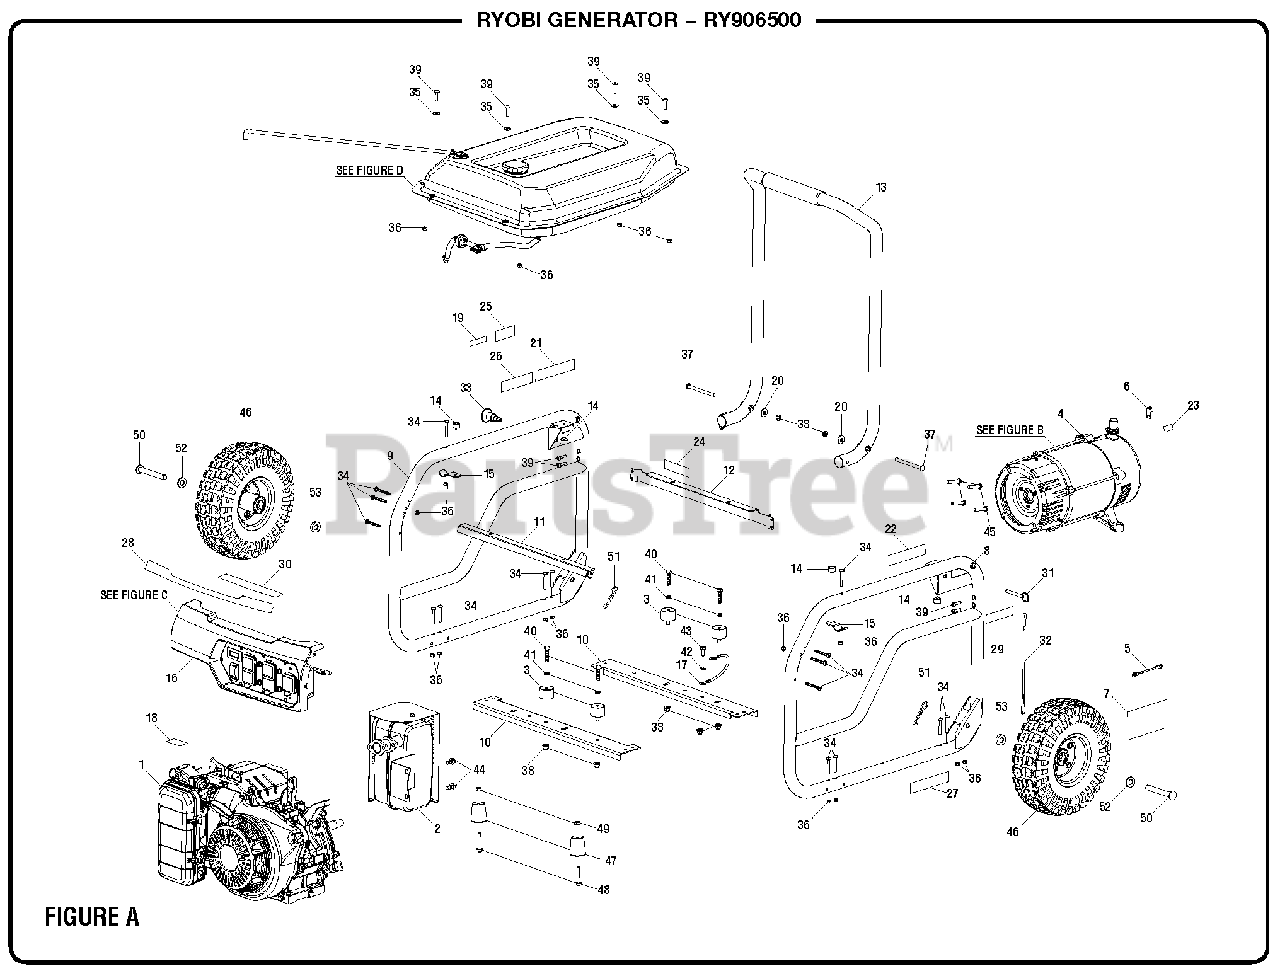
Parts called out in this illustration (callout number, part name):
1	Engine (Honda)
2	Muffler Assembly
4	Generator Head Assembly (See Figure B)
5	Bonding Wire
6	Ground Lug
7	Rubber Sheet
8	Frame Assembly (Right)
9	Frame Assembly (Left)
10	Cross Bar
11	Fuel Tank Support (Front)
12	Fuel Tank Support (Rear)
13	Handle Assembly
14	Handle Bumper
15	Handle Rest Tab
16	Control Panel Assembly (See Figure C)
17	Ground Wire Assembly
18	Choke Label
19	Inquiries Label
21	Fire Distance Label
22	Fire Danger Label
23	Ground Label
24	Ground Warning Label
25	Pull Pin Release Label
26	Hot Surface Label
27	Lubricant Label
28	Performance Label
29	Lock Pin Label
30	Quick Start Label
31	Release Pin
33	Handle Lock Assembly
34	Bolt (M6 x 50 mm, Torx Pan Hd. T30)
35	Washer (M6)
36	Lock Nut (M6)
37	Bolt (M8 x 98 mm, Flat Hd.)
38	Lock Nut (M8)
39	Bolt (M6 x 25 mm, Torx Pan Hd.)
40	Bolt (M8 x 35 mm, Hex Hd.)
41	Washer (M8)
42	Star Washer (M8)
43	Bolt (M8 x 15 mm, Hex Hd.)
44	Bolt (5/16-24 x 0.6 in.)
45	Bolt (3/8-16 x 1 in.)
48	Bolt (M8 x 45 mm, Hex Hd.)
49	Lock Nut (M8 x 1.25)
51	Hitch Pin
52	Washer (M10)
